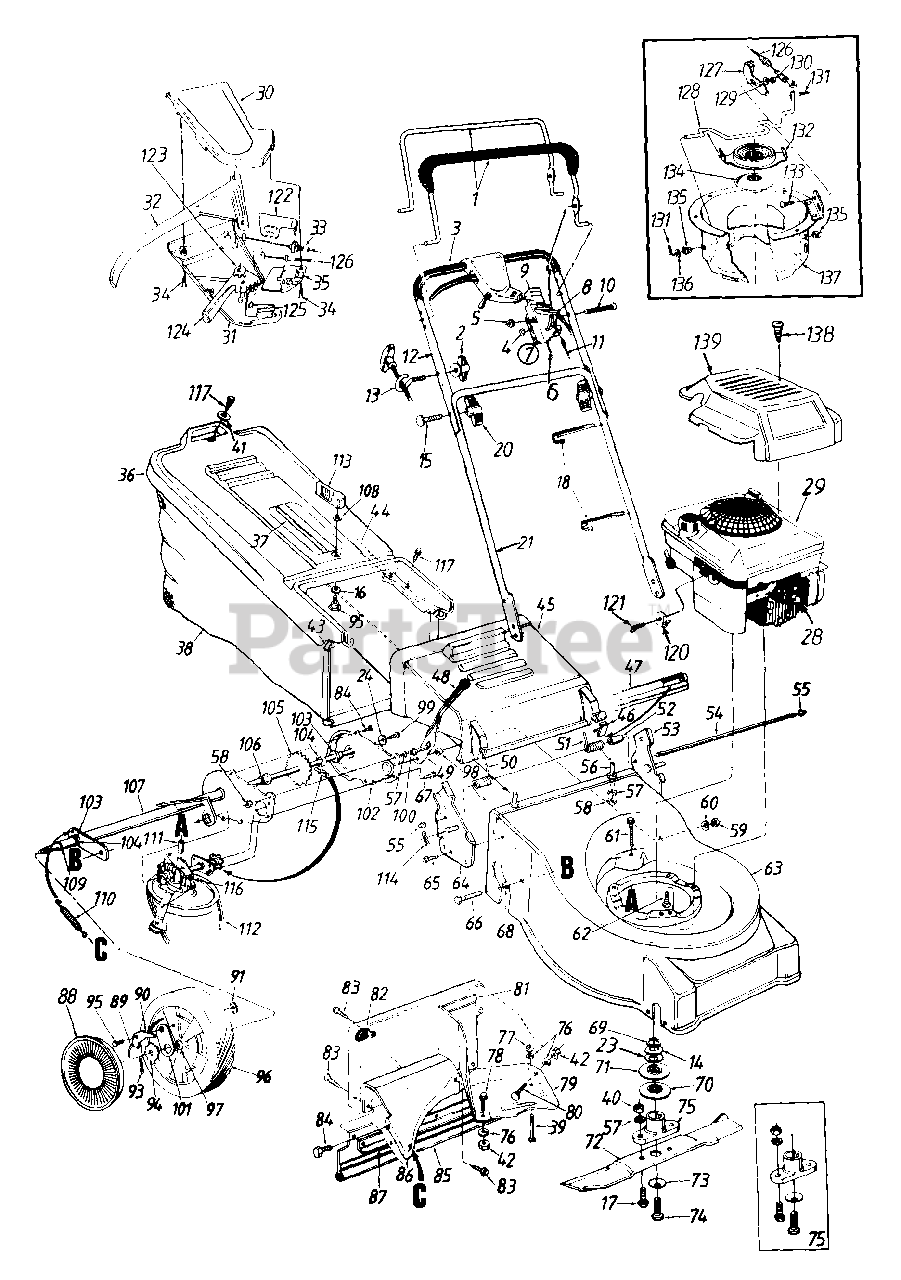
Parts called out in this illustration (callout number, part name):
2	Wing Nut 1/4-20 Thd.
3	Foam Grip
4	Spr. Wash..66" I.D.
5	Hex L-Nut 1/4-20 Thd.
6	Throttle Cable - 55"
7	Throttle Box Comp.
8	Throttle Lever
9	Throttle Body
10	Oval C-Sunk Scr.
11	Control Cable - 40.5"
12	Upper Handle
13	Rope Guide
15	Curved Hd. Bolt 5/16-18 x 2"
16	Bowed Washer
17	Hex Bolt 3/8-24 x 1" Lg.
18	Cable Tie
20	Hand Knob
24	Bell-Wash..265" I.D. x.75"
28	Spark Plug Boot
29	Engine
30	Control Cover Half - Upper
31	Control Cover Half - Lower
32	Control Lever
33	Drive Cable - 51" Lg.
34	Flat C-Sunk Hd, Tap Scr. 10 x .75" Lg.
35	S.P. Control Cover
36	Hardtop Bag Cover
37	Hardtop Handle
38	Grass Bag
39	Truss Mach. Scr. 1/4-20 x 1.0" Lg.
40	Hex Nut 3/8-24 Thd.
41	Fl-Wash..281" I.D. x .62"
42	Hex Nut 1/4-20 Thd.
44	Rear Catcher Frame
45	Chute Deflector
46	Deflector Plug
47	Seal - Extrusion
49	Spring Lever
50	Torsion Spring - R.H.
51	Torsion Spring - L.H.
52	Spacer .255" I.D.
55	Cap Speed Nut
56	Shld. Pin 3/8-24 x 1.43" Lg.
57	L-Wash. 3/8" I.D.
58	Hex Jam Nut 3/8-24 Thd.
59	Hex L-Nut 3/8-24 Thd.
60	Bell-Wash..38" I.D. x .88"
61	Hex Wash. Hd. Tap Scr. 1/4-20 x 1.5" Lg.
62	Hex L-Wash. Hd. Scr. 3/8-16 x 1" Lg.
63	21" Deck Ass'y.
66	Hex Wash. Hd. Tap Scr. 3/8-16 x .75" Lg.
67	Hex Wash. Hd. Tap Scr. 1/4-20 x .5" Lg.
68	Spacer .383" I.D.
72	21" Blade
73	Bell-Wash..46" I.D.
74	Hex Bolt 7/16-20 x 1.5" Lg.
75	Blade Adapter Kit
76	L-Wash. 1/4" I.D.
77	Hex Jam Nut 1/4-20 Thd.
78	Hex Bolt 1/4-20 x .85" Lg.
79	Rear Belt Baffle
80	Carr. Bolt 1/4-20 x .50" Lg.
83	Torx Mach. AB-Tap Scr. 1/4 x .62" Lg.
84	Hex B-Tap Scr. 1/4 x .38" Lg.
85	Rear Flap
89	Plastic Spring
90	Pawl .345" I.D.
91	Weld Top L-Nut 1/4-20 Thd.
93	Cotter Pin 1/8" Dia.
94	Ratchet Wheel 1.62" O.D.
95	Shld. Bolt .342" Dia. x .268"
96	Wheel Ass'y. Comp.- Rear
97	Bearing 1/2" I.D.
98	Shld. Spacer .50" Dia.
99	Hex Bolt 1/4-20 x .62" Lg. (Gr. 5)
100	Shld. Pin 3/8-24 x 1.43" Lg.
101	Pawl Plate
104	Fl-Wash..531" I.D. x .93"
105	Rear Axle Ass'y.
106	Hex Flange Bearing
109	Spacer .513" I.D.
110	Extension Spring 3.8" Lg.
111	Spacer .325" I.D.
112	V-Belt
113	Grass Catcher Locking Knob
114	Internal Cotter Pin 5/16" Dia.
115	#48 Chain .50" Pitch x 30 Links
116	Transmission Comp. (See Breakdown)
117	Hex L-Wash. Hd. AB-Tap Scr. 1/4 x .62" Lg.
120	Cable Clamp
121	Hex Self-Tap Scr. #10-32 x .62" Lg.
122	6-Speed Rack Cable Brkt.
123	3 Tooth Rack Gear Insert
124	6-Speed Shift Lever
125	Shift Lever Spring
126	Spd. Control Cable
129	Bell-Wash..265" I.D. x .75"
130	Hex Cent. L-Nut 1/4-20 Thd.
131	Cot-Pin 3/32" Dia. x .75" Lg.
132	Movable Pulley Half Ass'y.
133	Carr. Bolt 1/4-20 x .5" Lg.
134	Splined Pulley Half
135	Flanged Bushing
136	Fl-Wash..328" I.D. x.68" O.D.
139	Engine Shroud (Red)
